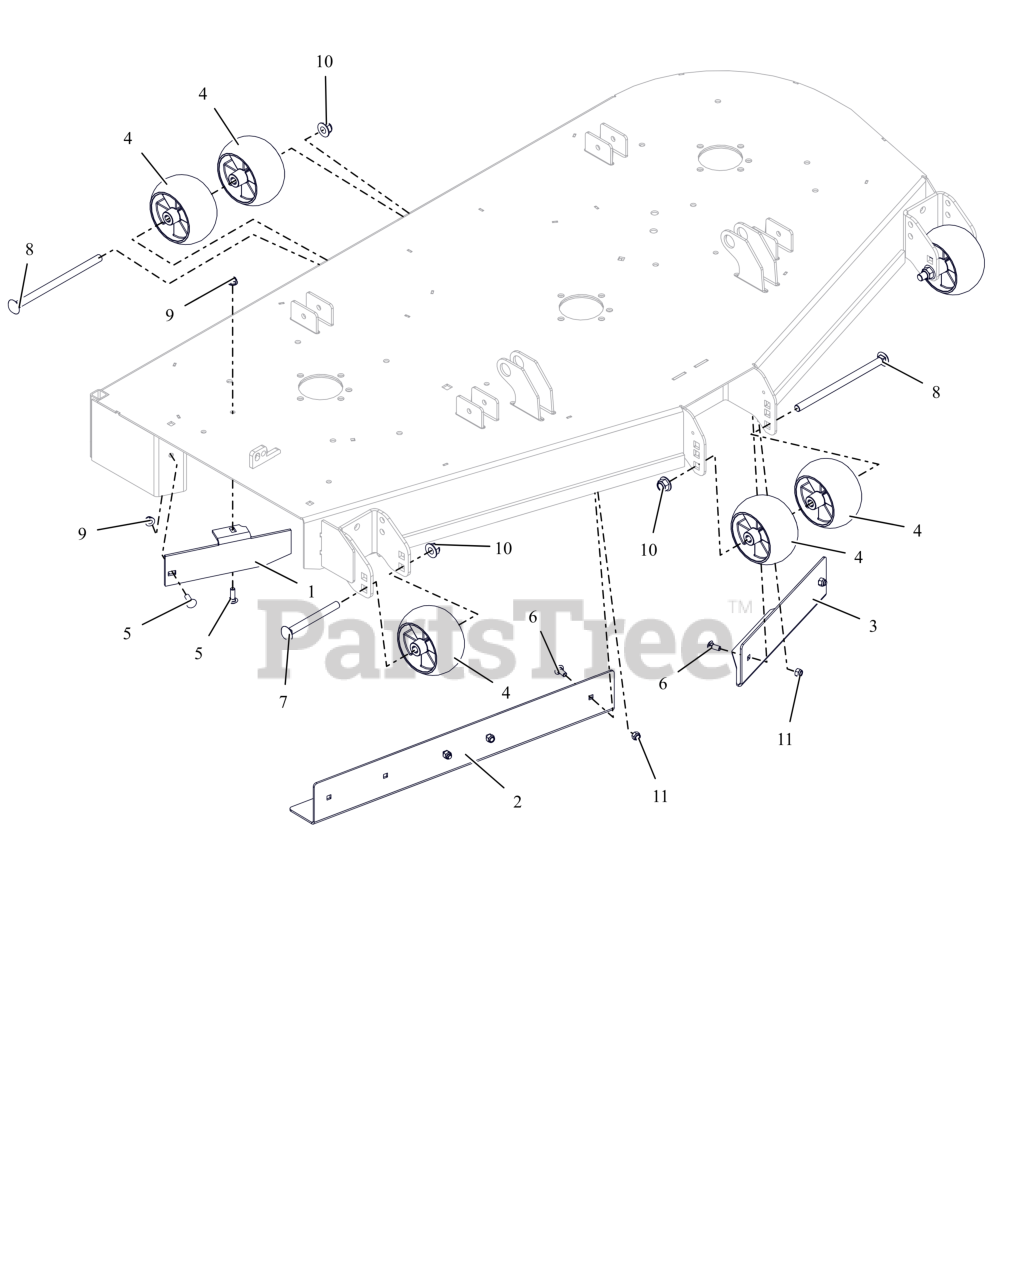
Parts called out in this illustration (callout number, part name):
1	60" DISCHARGE BAFFLE - RED
2	BAFFLE, 60" RH VACUUM (RED)
3	BAFFLE, 60" LH VACUUM (RED)
4	WHEEL, ANTI SCALP - 5X3 CTR W/RIBS
5	BLT,RHSN .31-18X1.00 G5 ZCC
6	BLT,RHSN .31-18X.75 G5 ZCC
7	BLT, RHSN .50-13X5.00 G5 ZCC
8	BTL,RHSN .500-13 X 8.5S G5 ZCC
9	NUT,NYL-FLG .31-18 GF ZCC
10	NUT,NYL-FLG .50-13 GF ZCC
11	NUT,NYL .31-18 G5 ZCC
